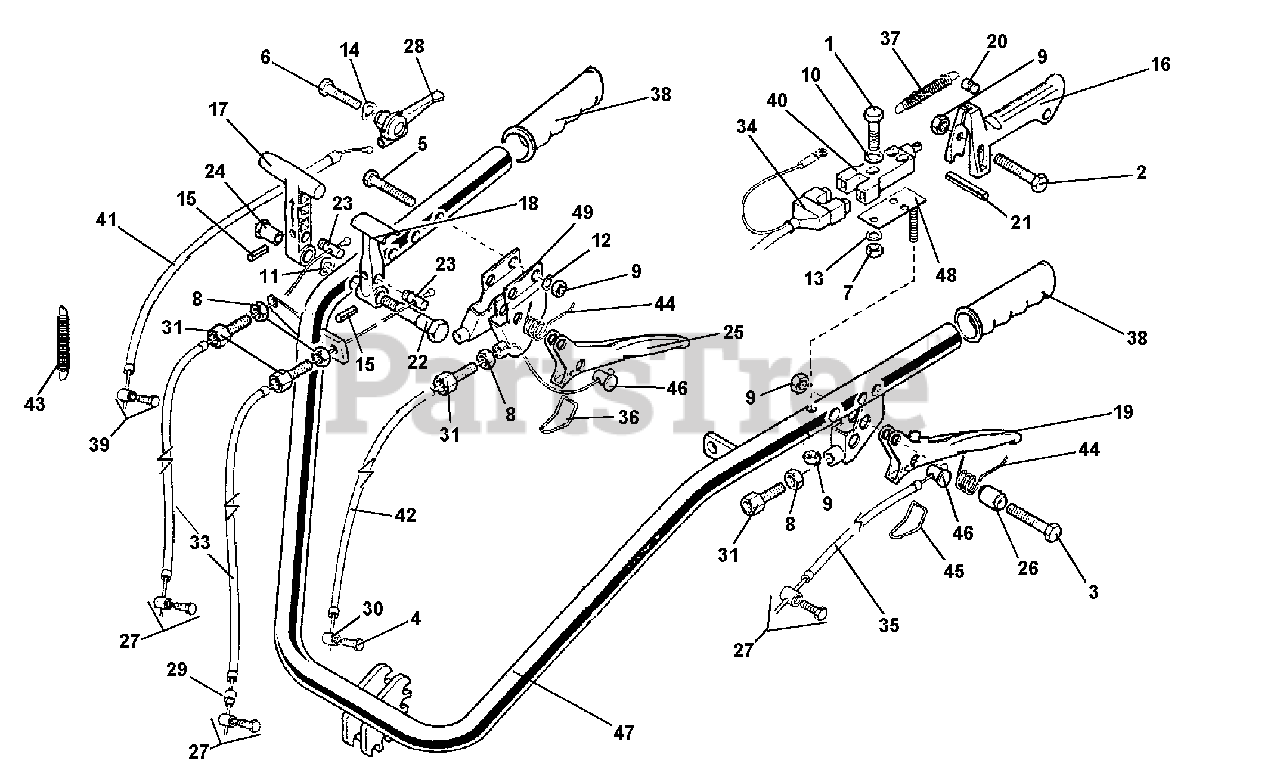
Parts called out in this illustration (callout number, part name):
1	SCREW, M4X25
2	SCREW, M6X45
3	SCREW, M6X25
4	SCREW, M6X16
5	SCREW, M6X35
6	SCREW, M8X35
9	NUT, SELF LOCKING, M6
10	FLAT WASHER, M4.3
12	WASHER, LOCK, M6.4
13	LOCK WASHER, M4.3
14	WASHER, LOCK, M8.4
15	PIN, LOCKING, M4X20
16	MOTOR STOP LEVER
17	REVERSER LEVER
18	LEVER DIFFERENTIAL LOCKING
19	CLUTCH LEVER
21	LEVER STOP FOR MOTOR STOP
23	DRILLED PIN
24	DRILLED PIN
26	LEVER SPACER
27	CLAMP, CABLE
28	LEVER, ACCELERATOR
30	PIN, CABLE CLAMP
31	SCREW, ADJUSTING M8
32	CABLE, REVERSE
33	CABLE, DIFFERENTIAL
34	SWITCH WIRING HARNESS
35	CLUTCH CABLE
39	CLAMP, CABLE, VANGARD
40	STOP SWITCH
41	THROTTLE CABLE, VANGARD
42	CABLE, BRAKE
43	SPRING, KOHLER
44	LEVER SPRING
47	HANDLE ASSEMBLY
48	SWITCH PLATE
49	COUPLING FOR DOUBLE LEVER
